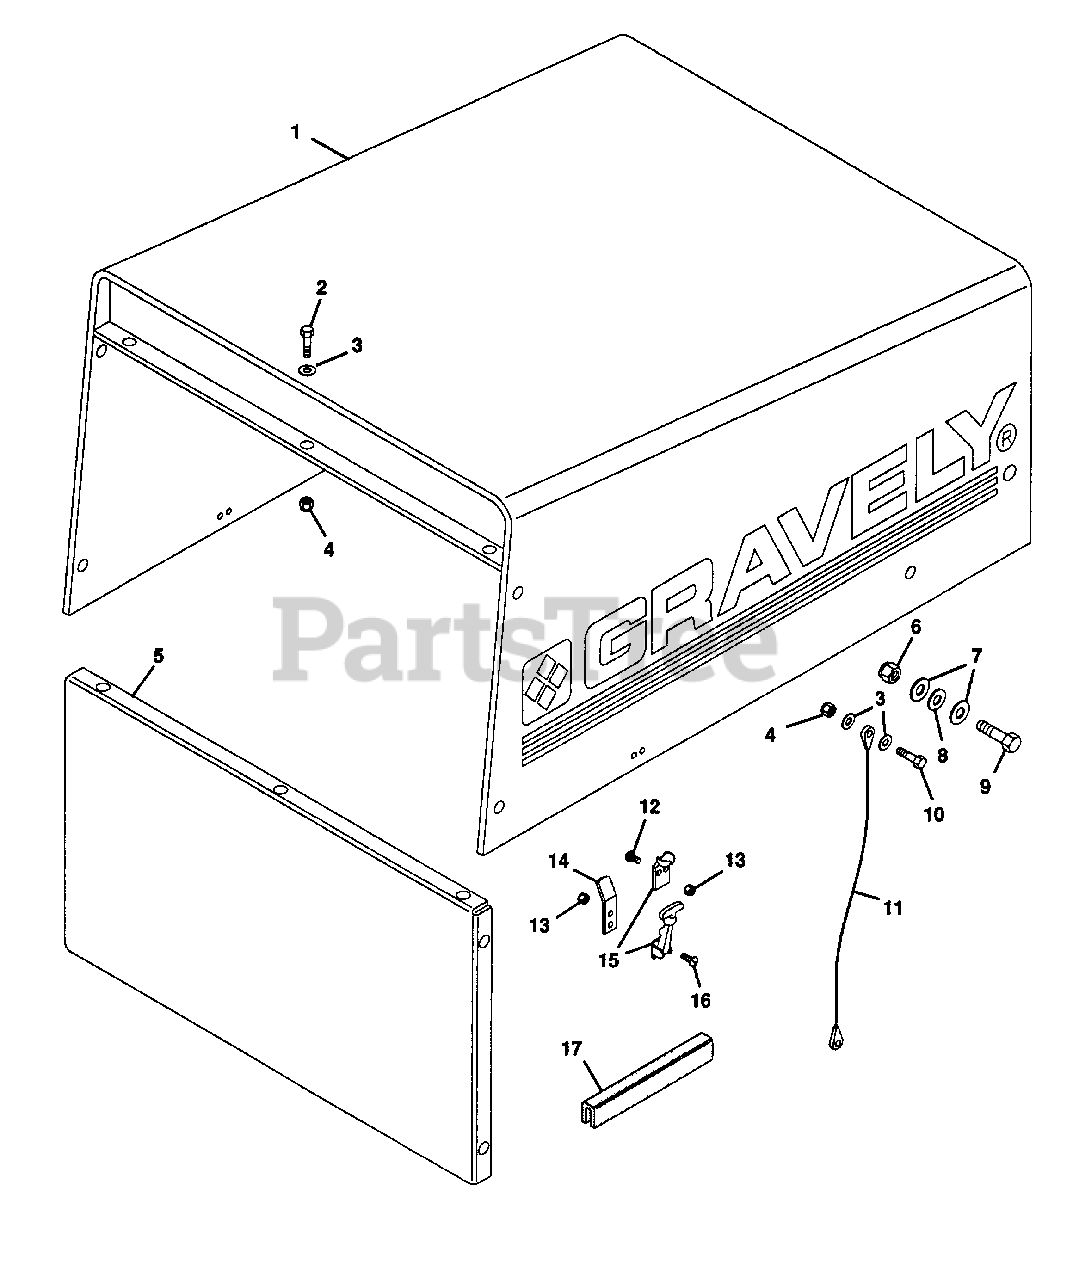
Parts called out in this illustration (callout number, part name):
1	Hood, Silk Screen
2	Bolt, Hex 1/4-20x.625
3	Washer, Flat .281x.625x.065
4	Nut, Lock 1/4-20
5	Panel, Hood
6	Nut, Lock 3/8-16
7	Washer, Flat .406x.812x.065
8	Washer, Nylon .375x.75x.060
9	Bolt, Hex 3/8-16x.875
10	Bolt, Hex 1/4-20x.875
11	Cable, Hood
12	Screw, Machine 10-24x.50 PHD
13	Nut, Lock 10-24
14	Plate, Guide
15	Latch
16	Screw, Machine 10-24x.75 PHD
17	Cowl Strip,
